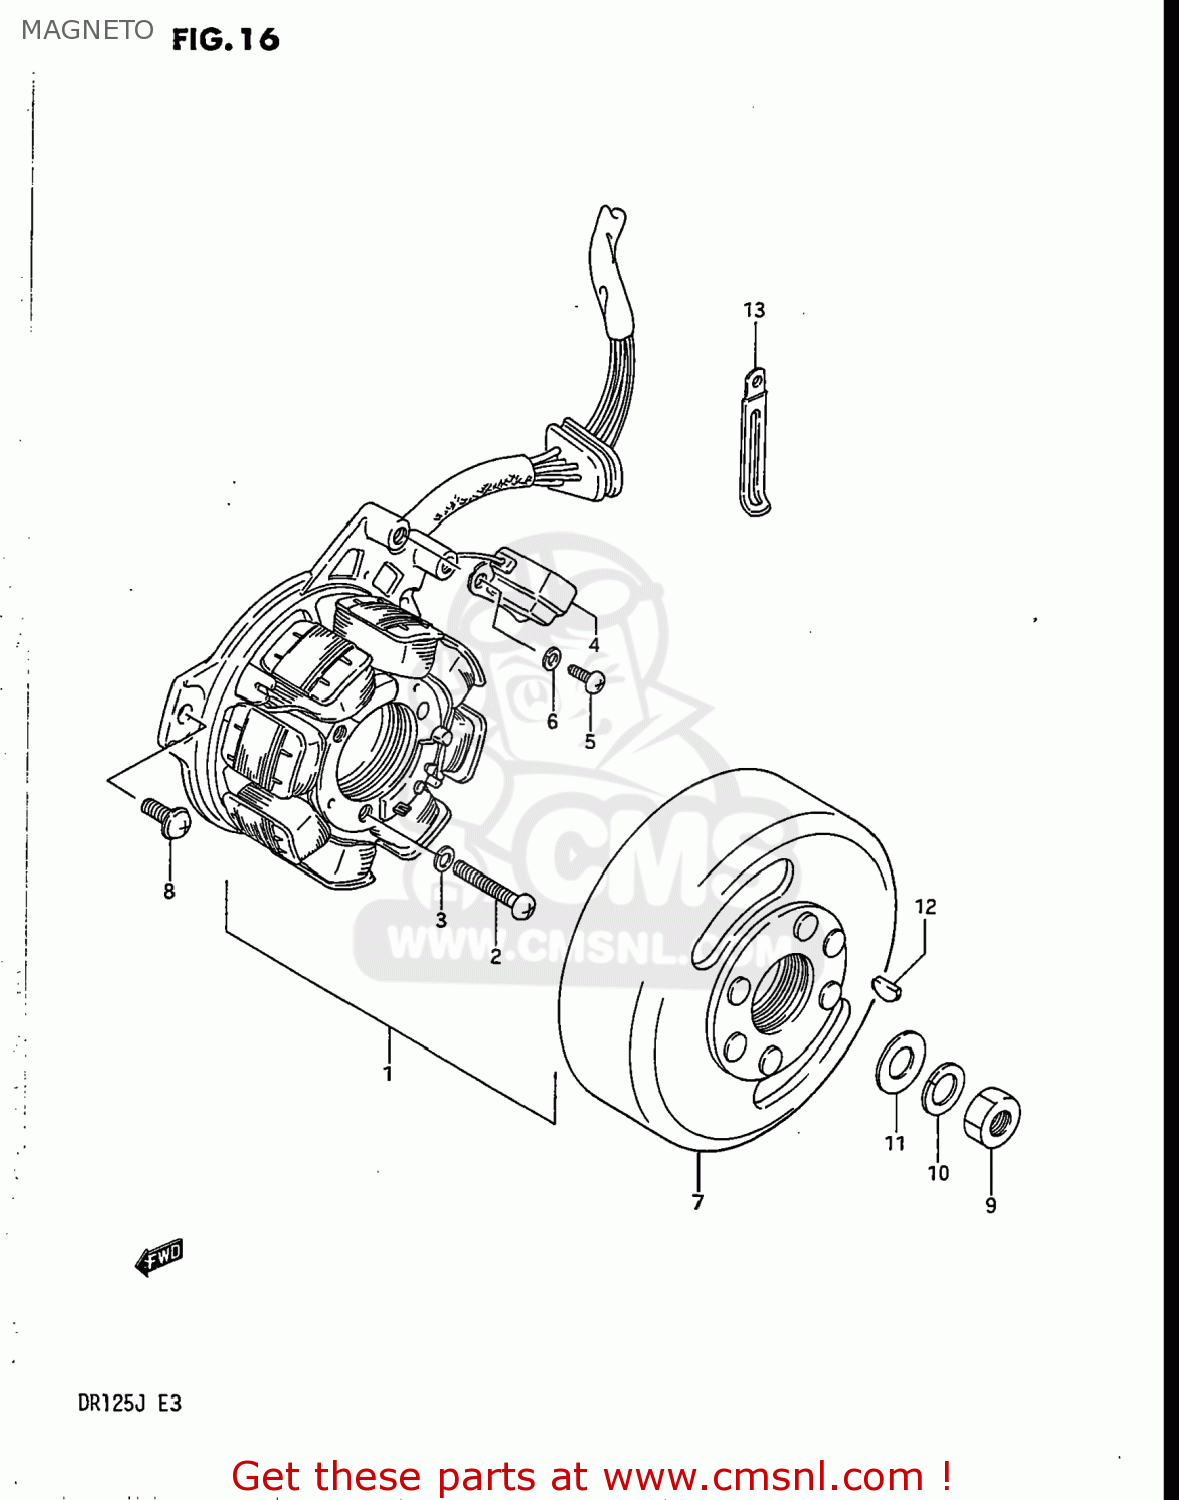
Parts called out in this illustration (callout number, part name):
1	STARTER ASSY
2	SCREW
3	LOCK WASHER
4	COIL,PICK UP
5	SCREW
6	WASHER,LOCK 4M
7	ROTOR ASSEMBLY
8	SCREW(5X14)
9	NUT (10MM)
10	WASHER,LOCK,10
11	WASHER
12	KEY
13	CLAMP
